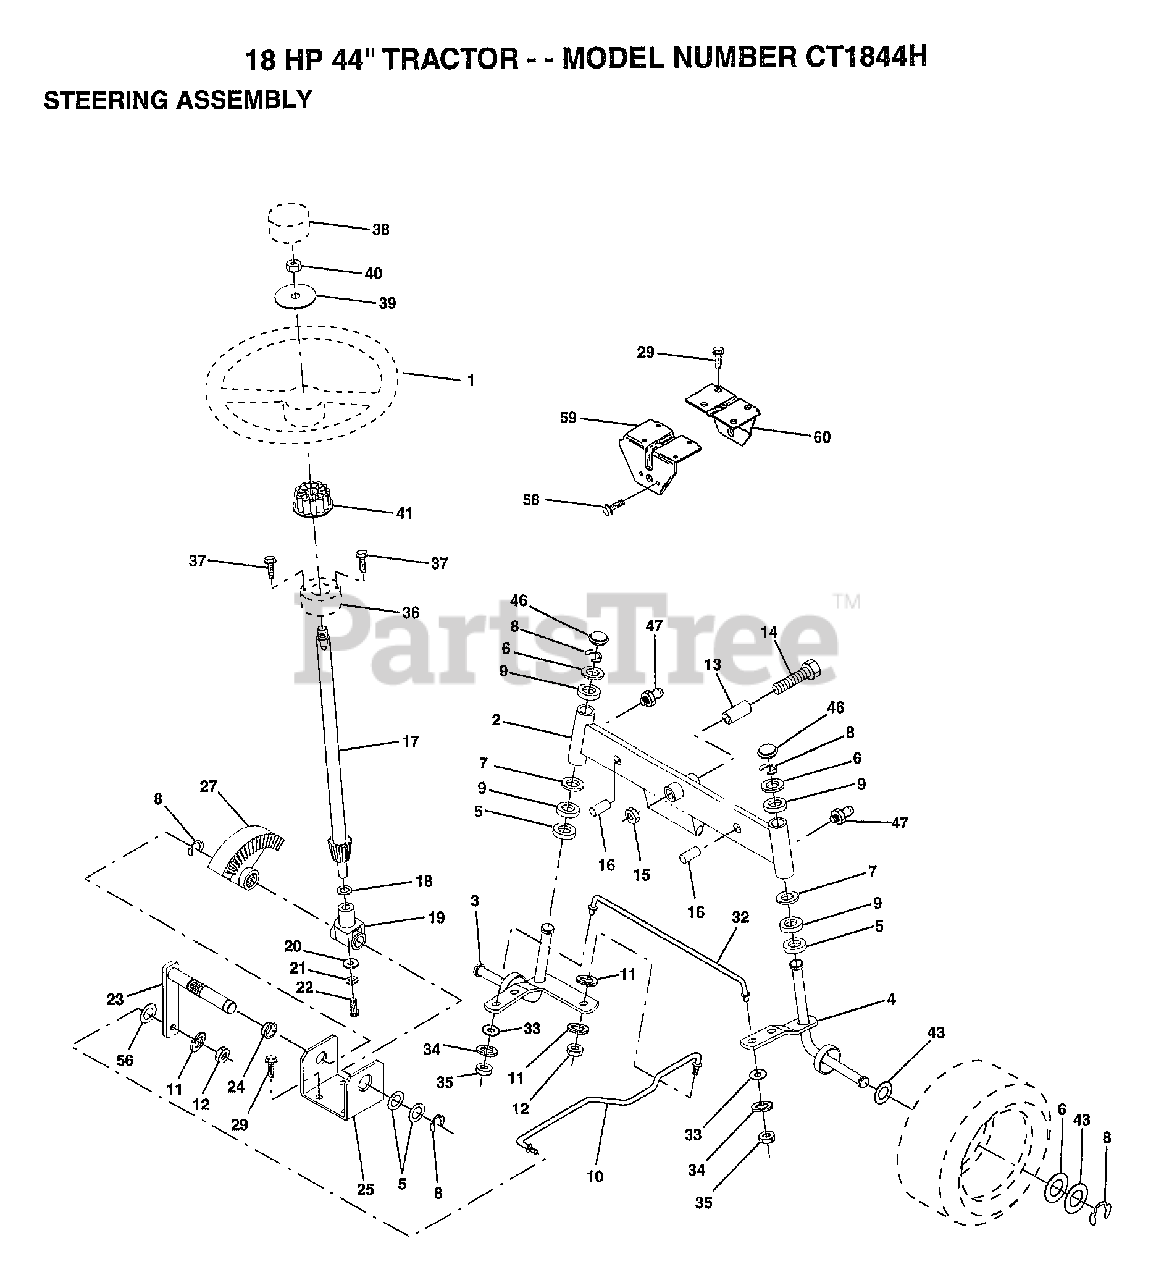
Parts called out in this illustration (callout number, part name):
1	WHEEL STR AYP BLK
2	AXLE ASM FRONT
5	WASHER .T
6	WASHER
7	WASHER
8	RING
9	COL. SRTG. BEAR.
11	LOCKWASHER
13	BEARING
14	BOLT LT
15	"NUT-LOC,FLANGE LT"
16	AXLE PIN
18	THRUST WASHER
19	SUPPORT.SHAFT
21	LOCKWASHER
22	"SCREW,SPECIAL"
24	NYLINER T
25	"BRKT,STEERING"
27	GEAR SECTOR
29	SCREW
32	TIE ROD
33	WASHER M
34	LOCKWASHER
35	NUT.LOCK.5/16-24
38	CAP STEER AYP
39	WASHER
41	ADAPTER LT
43	WASHER
46	CAP
47	ZERK M
56	WASHER
58	SCREW LT
59	SUPPORT-SADDL T
60	SUPPORT.SADDLE.FT
